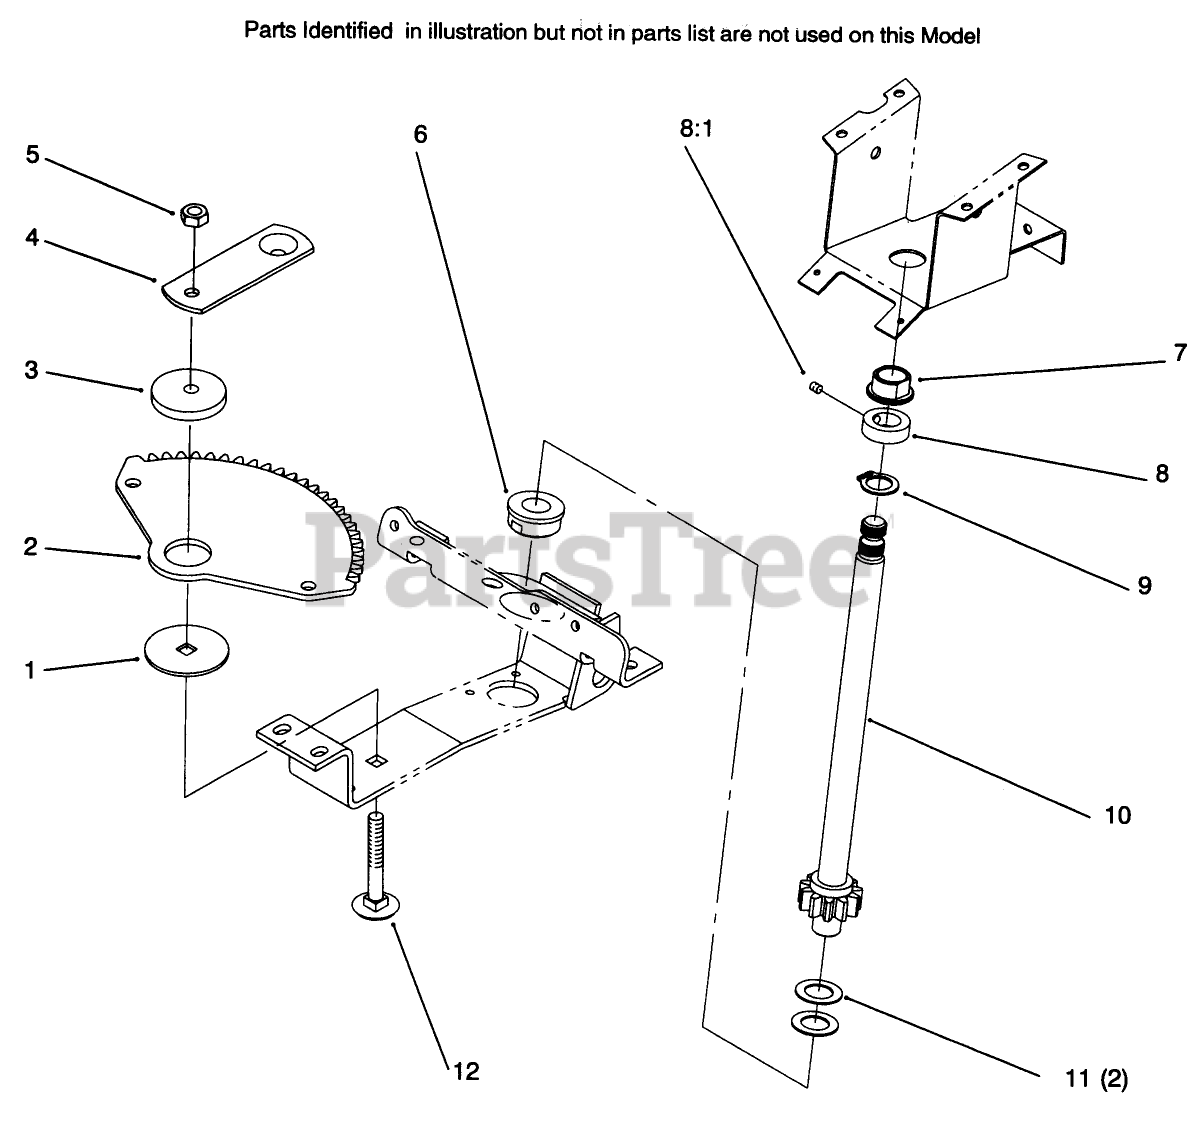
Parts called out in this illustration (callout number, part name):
1	WASHER-BEARING
3	BUSHING
5	NUT-HEX
6	BEARING-WHEEL
7	BEARING-FLANGED
8	COLLAR
8:1	SCREW-HSH
9	RING-RETAINING
10	SHAFT-STEERING, LOWER
11	WASHER
12	SCREW-CARR
